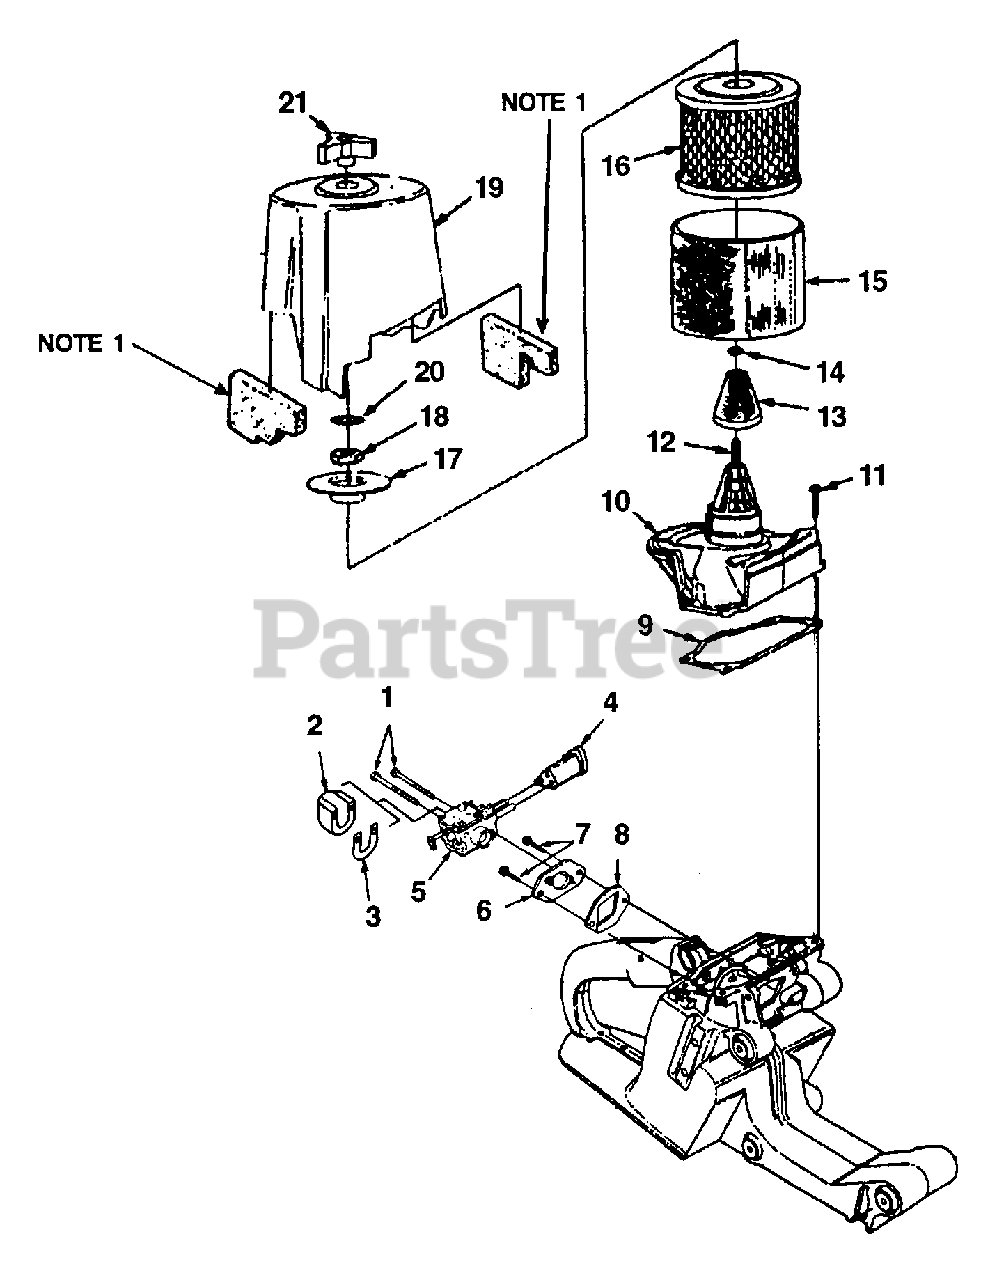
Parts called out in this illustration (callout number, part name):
1	SCREW-Hex Cap (10-14 x 2")
2	SHIELD-Carburetor
3	GASKET-Carburetor Shield
5	CARBURETOR
6	ADAPTER-Carburetor
7	SCREW-Torx Truss (10-24 x 1/2")
8	GASKET-Carburetor
9	GASKET-Carb. Chamber
10	COVER-Carb. Chamber
11	SCREW-Pan Hd. (8-32 x 5/8")
12	BOLT
13	FILTER-Air
14	"O" Ring
15	FELT PREFILTER
16	ELEMENT-Air Filter
17	AIR FILTER ELEMENT COVER
18	NUT-Hex (5/16-18)
19	FILTER COVER
21	RETAINING RING
NOTE1	FOAM KIT
